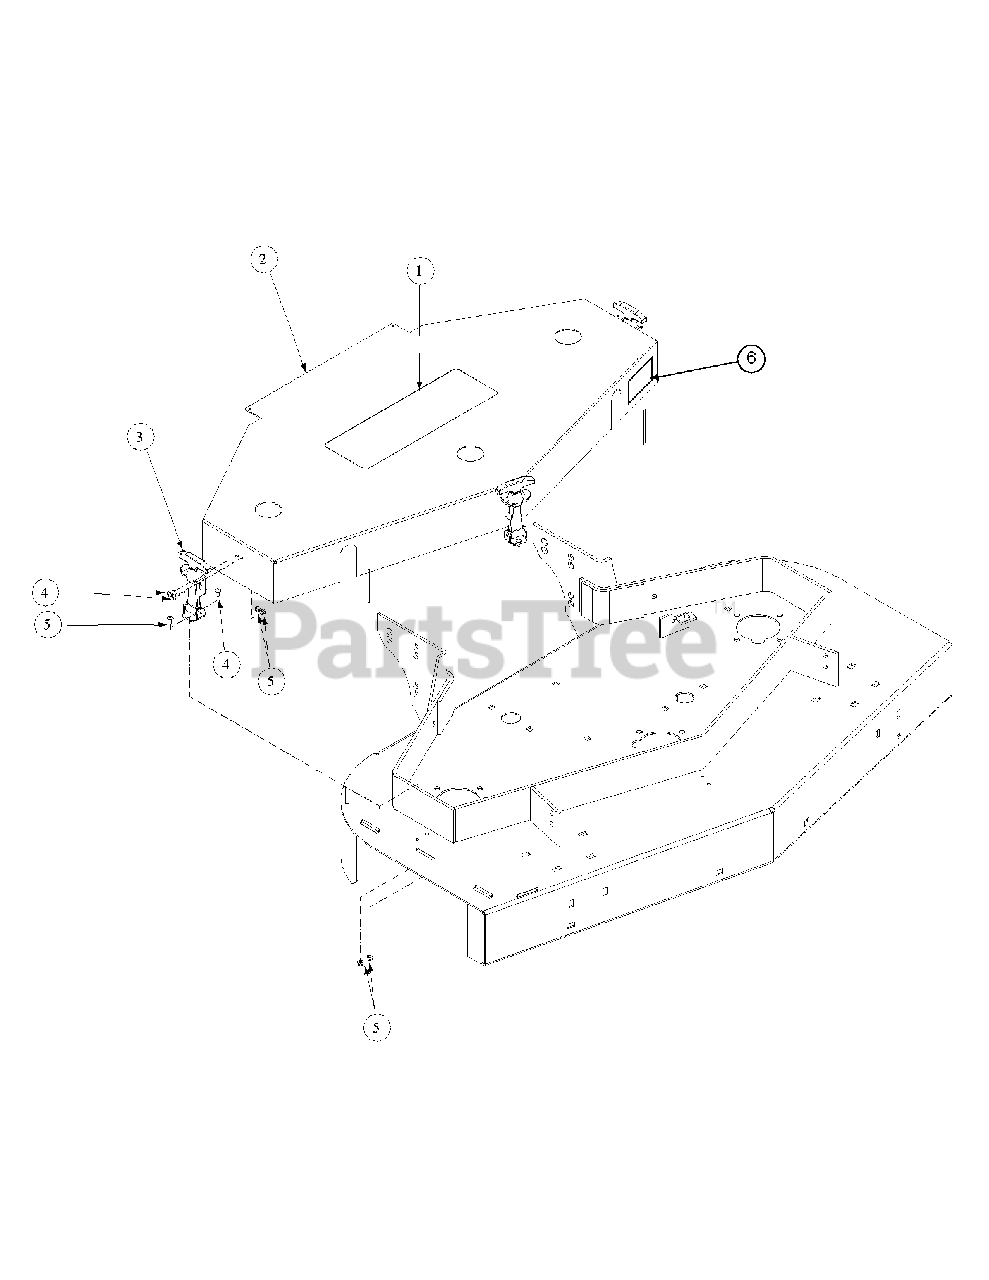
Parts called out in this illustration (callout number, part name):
1	Label Commercial Mower
2	Deck Cover 48"
3	Rubber Latch Hood
4	Machine Screw, 10-24 x 1/2
5	Lock Nut, Nylon Insert, #10-24
6	Label, H1748
